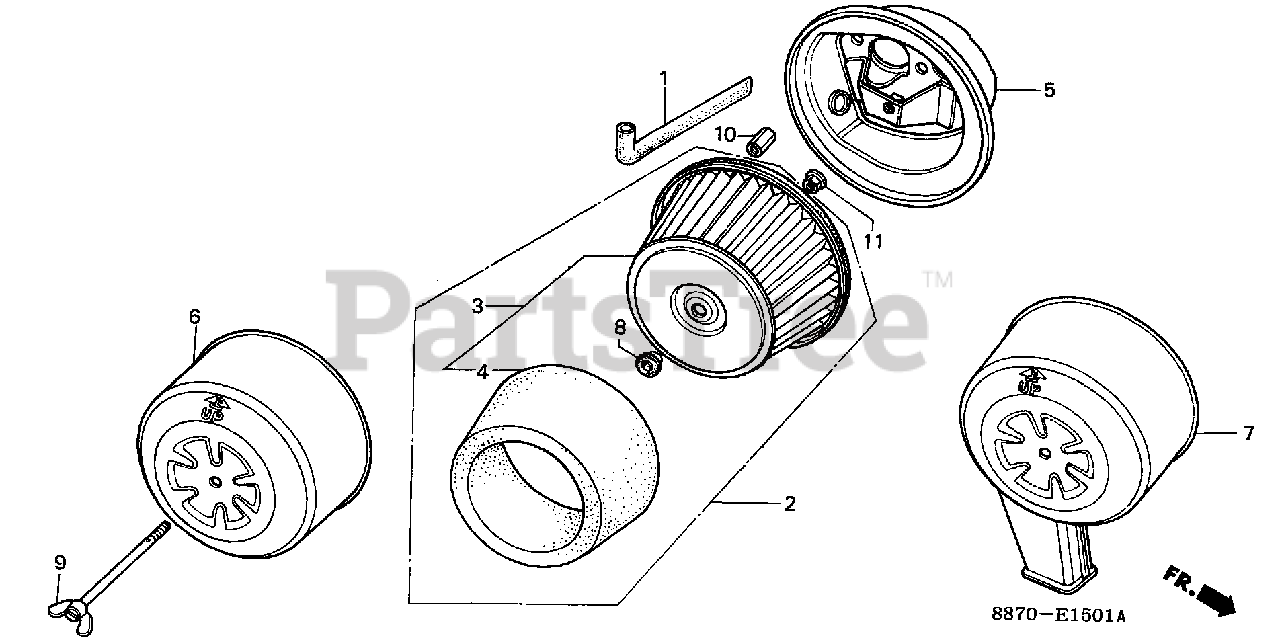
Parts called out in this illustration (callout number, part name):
1	TUBE, BREATHER Use from Engine SN 1194247 to 1381354.
1	TUBE, BREATHER Use from Engine SN 1381355.
3	ELEMENT, AIR CLEANER Use from Engine SN 1194247 to 2014339.
3	ELEMENT, AIR CLEANER Use from Engine SN 2014340.
4	ELEMENT B, AIR CLEANER Use from Engine SN 1541113.
5	HOUSING, AIR CLEANER Use from Engine SN 1194247.
7	COVER, AIR CLEANER Use from Engine SN 1194247.
8	GROMMET, AIR CLEANER Use from Engine SN 1194247.
9	BOLT, AIR CLEANER COVER Use from Engine SN 1194247.
10	NUT (6X15) Use from Engine SN 1194247 to 1366847.
11	NUT, FLANGE (6MM)
